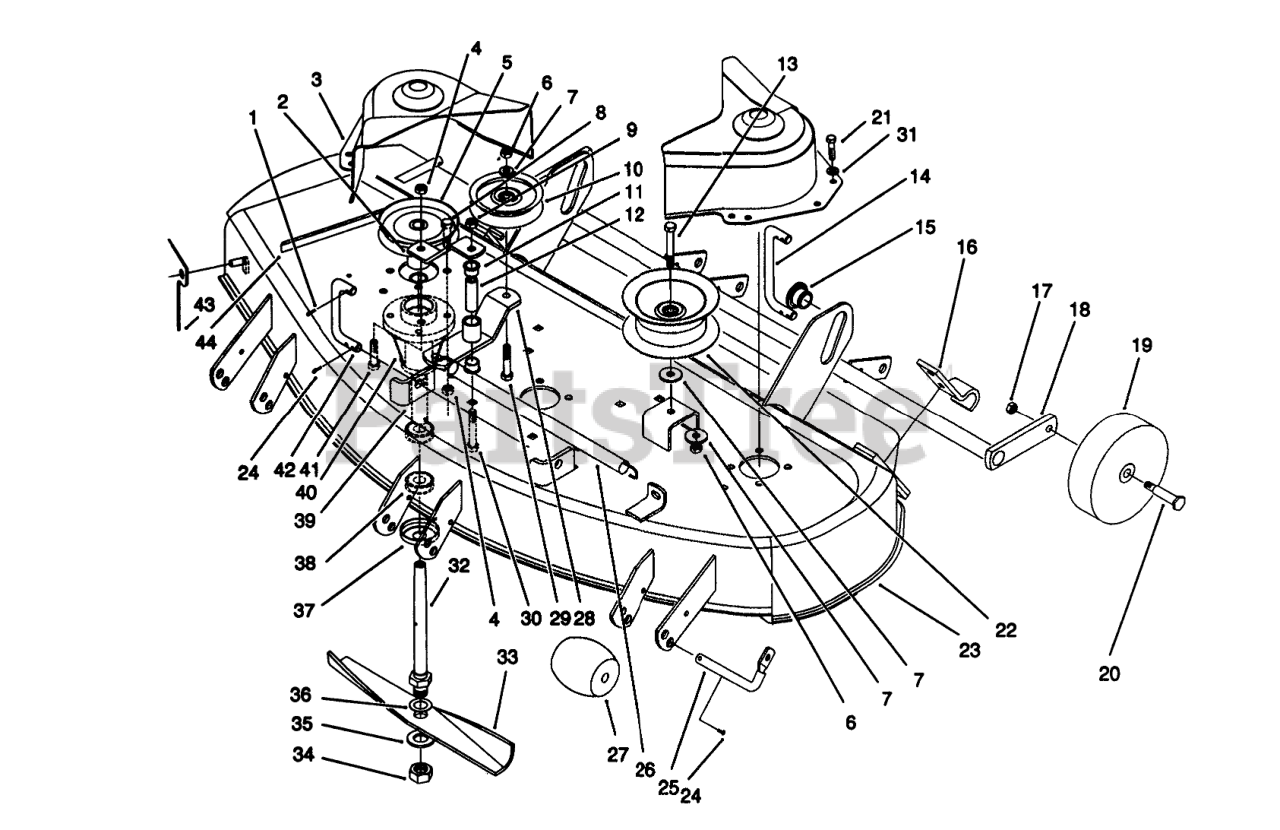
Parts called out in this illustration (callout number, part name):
1	Hairpin
3	COVER-BELT
4	NUT-LOCK, NI
6	NUT-LOCK, NI
7	WASHER-FLAT
9	NUT-LOCK, NI
11	BUSHING
12	SPACER
13	SCREW-HH
14	LINK-REAR
15	ROLLER-LIFT
19	WHEEL
20	BOLT-SHOULDER
21	Bolt
24	PIN-COTTER
26	SPRING-EXTENSION
27	ROLLER
29	SCREW-HH
30	SCREW-HH
31	WASHER-FLAT
32	SHAFT-SPINDLE
33	BLADE KIT (3 PACK)
34	NUT-JAM
35	WASHER-FLAT
38	BEARING-BALL
40	HOUSING-SPINDLE
41	SCREW-HH
